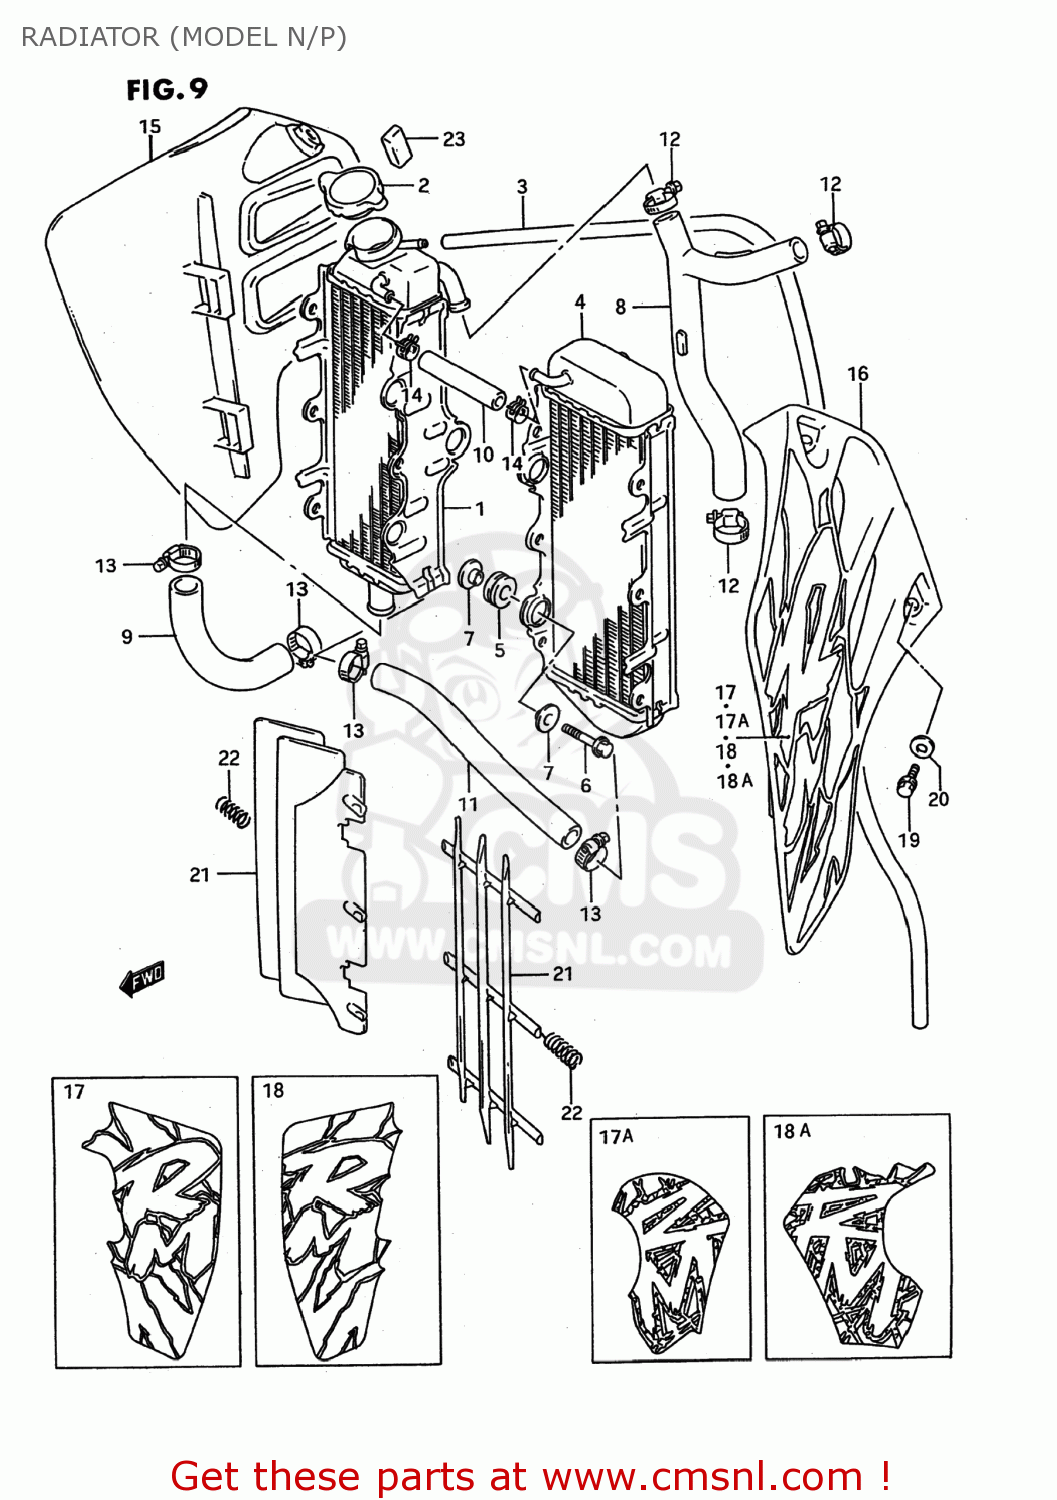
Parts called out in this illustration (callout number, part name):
1	RADIATOR ASSEMBLY,WATER
2	CAP,RADIATOR 1.1
3	HOSE
4	RADIATOR ASSEMBLY,WATER
5	CUSHION,RADIATOR LWR
6	BOLT
7	WASHER,RDTR SPRT
8	HOSE,RADIATOR INLET
9	HOSE,RADIATOR OUTLET
10	HOSE,WATER
11	HOSE,RADIATOR JOINT
12	CLAMP
13	CLAMP
14	CLIP
15	COVER,RADIATOR
16	COVER,RADIATOR
17	EMBLEM,RADIATOR COVER
17A	EMBLEM,RADIATOR COVER
18	EMBLEM,RADIATOR COVER
18A	EMBLEM,RADIATOR COVER
19	BOLT
20	GASKET(6.5X20X1.5) (NAS)
21	LOUVER,RADIATOR
22	SPRING
23	CUSHION,RADIATOR COVER
